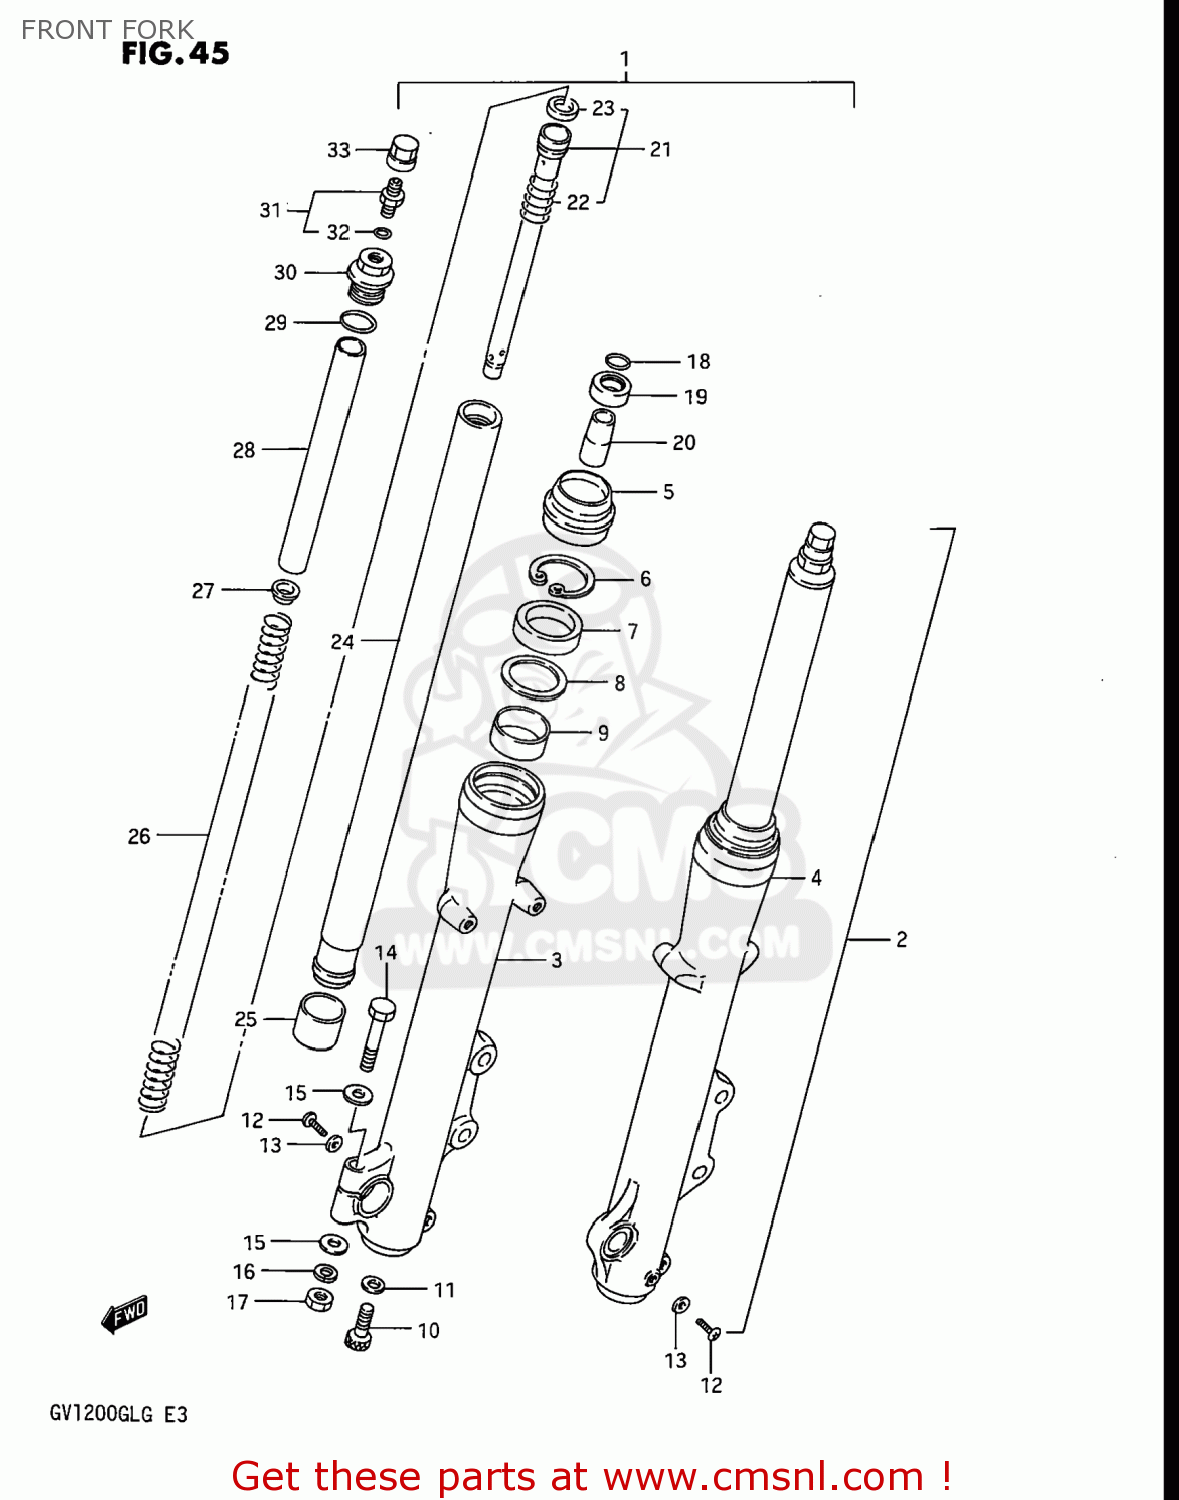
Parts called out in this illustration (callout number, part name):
1	DAMPER ASSEMBLY,FRONT FORK,RIGHT
2	DAMPER ASSEMBLY,FRONT FORK,LEFT
3	TUBE,FORK,OUTER,RIGHT
4	TUBE,OUTER,LEFT
5	DUST SEAL,FRONT FORK
6	RING,OIL SEAL STOPPER
7	OIL SEAL,FRONT FORK
8	WASHER,FORK OIL SEAL
9	METAL,SLIDE
10	BOLT,CYLINDER
11	GASKET,CYLINDER (NAS)
12	SCREW
13	GASKET,DRAIN,PLUG (NAS)
14	BOLT 8X50
15	WASHER
16	WASHER,LOCK,8.
17	NUT
18	RING,SNAP
20	PIECE,OIL LOCK
21	CYLINDER,FRONT FORK
22	SPRING,REBOUND
23	RING,PISTON
24	TUBE,FORK,INNER
25	METAL,SLIDE FR FORK
26	SPRING,FRONT FORK
27	GUIDE
28	SPACER,FRONT FORK SPRING
29	O RING
30	BOLT,FORK INNER TUBE
31	VALVE,FRONT FORK AIR
32	O-RING
33	CAP,FRONT FORK AIR VALVE
